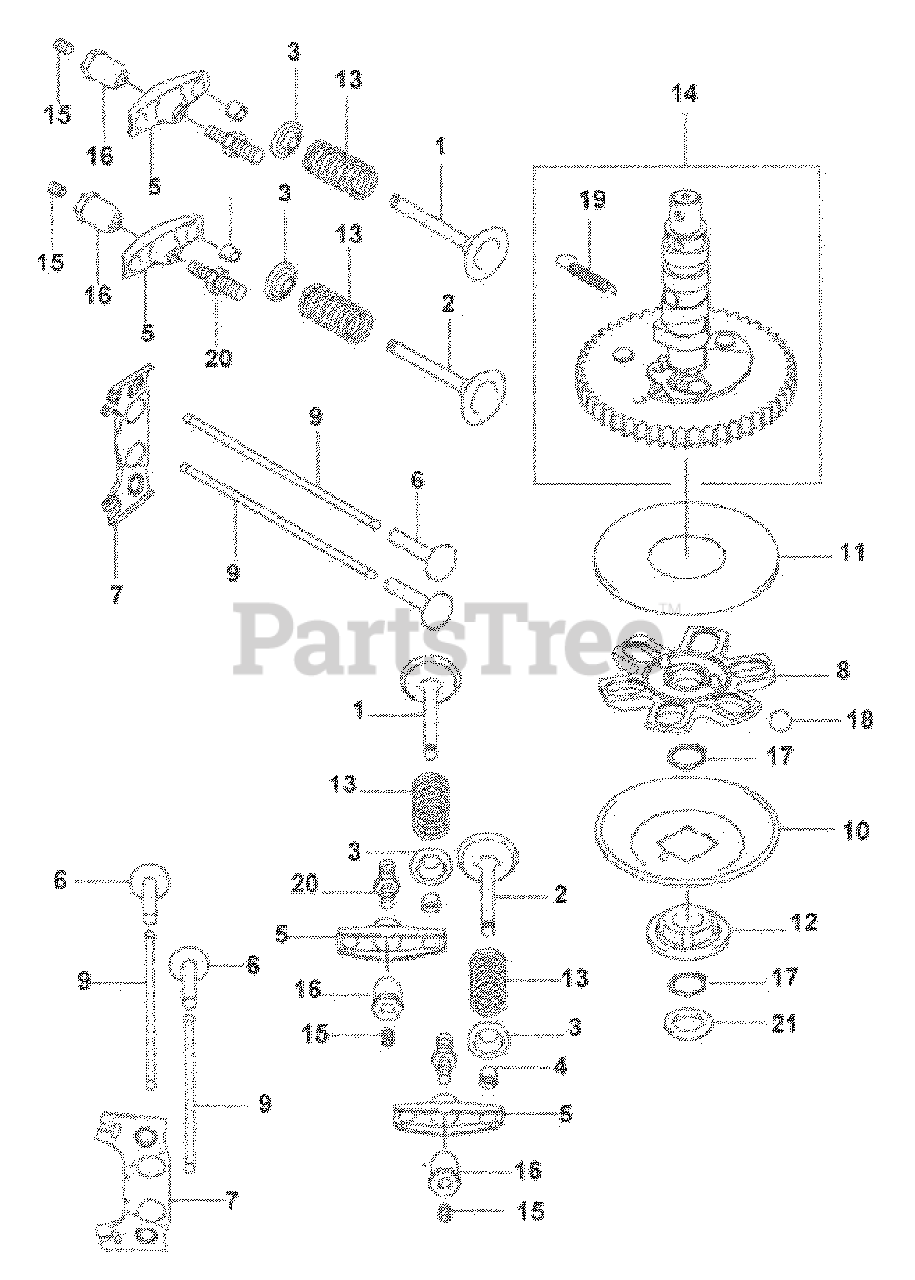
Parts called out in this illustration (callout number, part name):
1	Intake Valve
2	Exhaust Vale
3	Valve Spring Retainer
5	Rocker Arm
10	Governor Plate
12	Sleeve
17	Snap Ring
18	Ball
19	Spring
